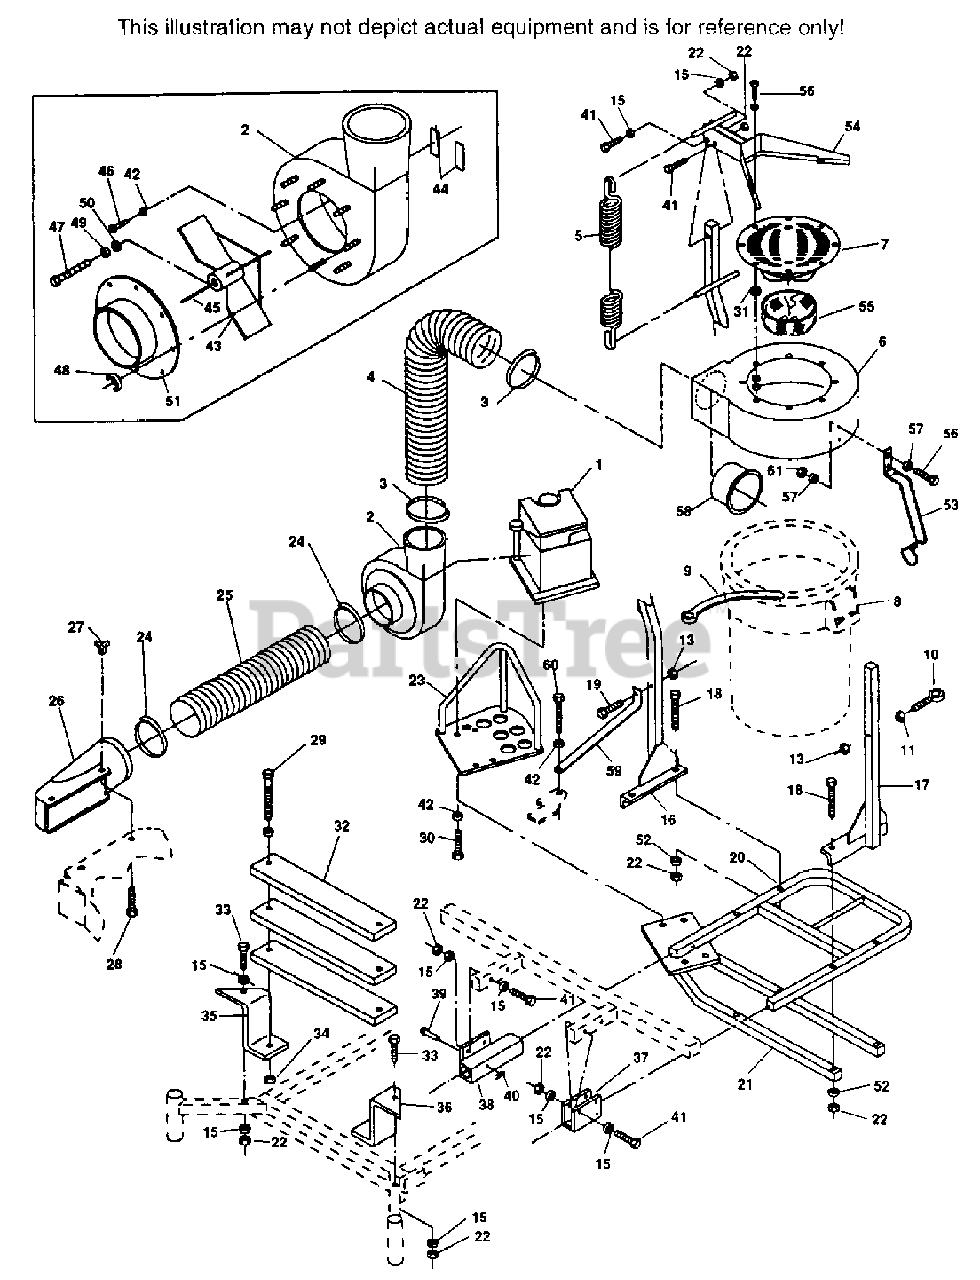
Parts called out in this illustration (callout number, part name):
1	KOHLER ENGINE 5HP
2	BLOWER HOUSING
3	HOSE CLAMP 6"
4	HOSE 6"ID X 34" LONG
5	SPRING
6	MOLDED TOP
7	FILTER SUPPORT
8	BUCKET
9	RUBBER STRAP
10	EYEBOLT, 5/16-18 X 2-3/4"
15	FLAT WASHER, 3/8"(.938 X .391 X 12 GA.)
16	UPRIGHT POST - RH
17	UPRIGHT POST - LH
20	CATCHER, BARREL SUPPORT FRAME
21	ENGINE MOUNTING FRAME
23	ENGINE GUARD
24	HOSE CLAMP 8"
25	HOSE 8"ID X 37" LONG
26	BOOT
27	ELASTIC WING NUT, 3/8-16
31	SPACER
32	WEIGHT BAR
35	WEIGHT BAR MOUNTING BRACKET, RH
36	WEIGHT BAR MOUNTING BRACKET, LH
37	CATCHER SUPPORT, L.H.
38	CATCHER SUPPORT, R.H.
39	CLEVIS PIN
40	HAIR PIN
44	SPACER
45	KEY, 1/4 X 1/4 X 1-1/2"
48	ELASTIC WING NUTS, 5/16-18
51	INLET ADAPTER
52	WASHER, 3/8(1.5 X .406 X 7 GA.)
53	CONTAINER LATCH
54	COVER BRACKET WELDMENT
55	MESH FILTER
58	INTAKE NOZZLE
59	BRACE
